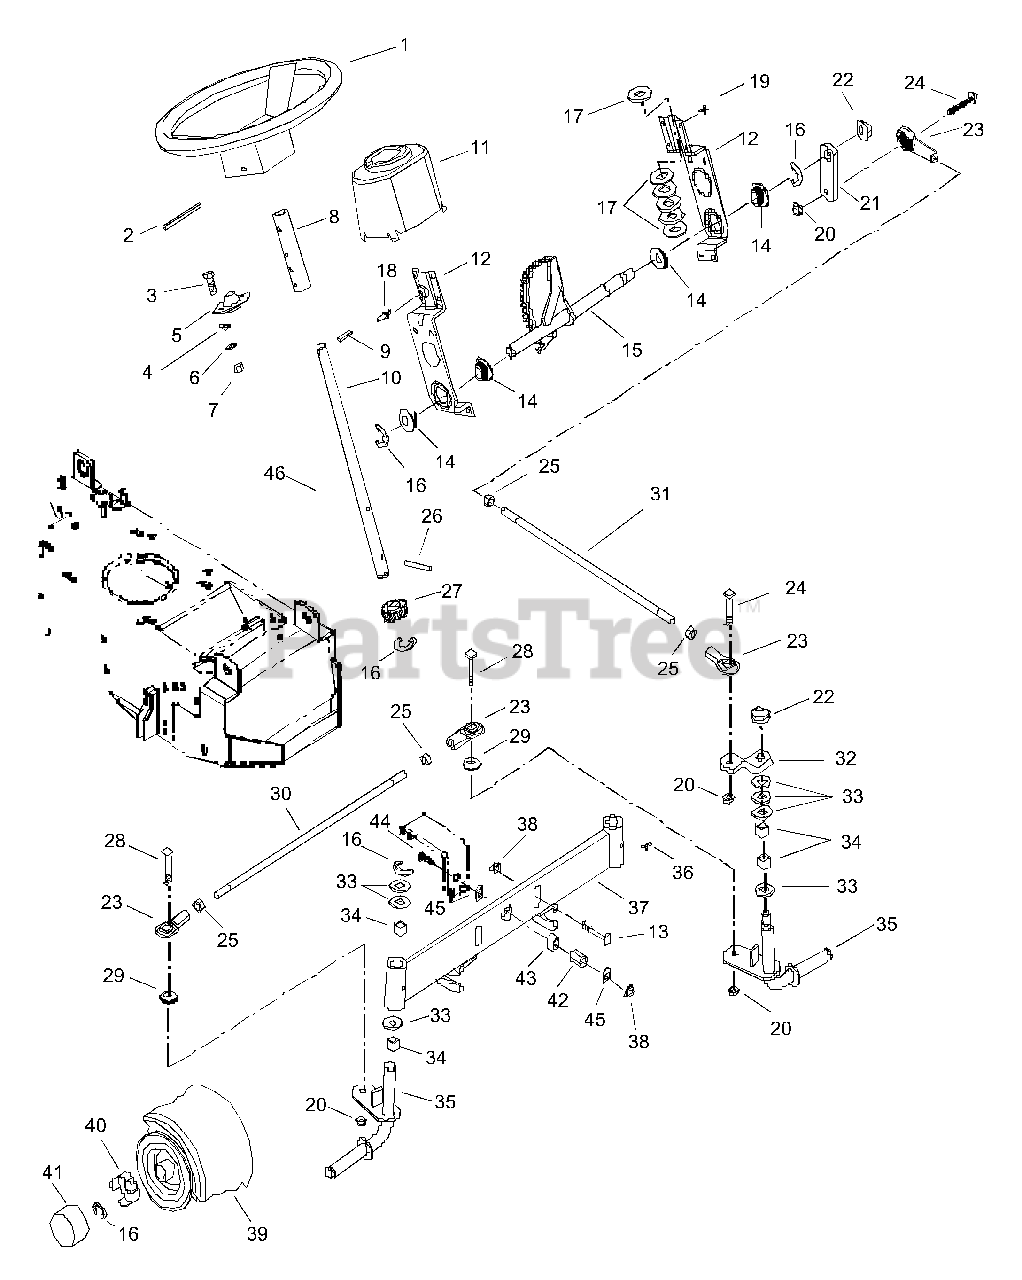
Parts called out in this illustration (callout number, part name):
1	Steering Wheel 13"
2	Pin-Roll .250 x 1.75
3	Bolt-Hex .31-18 x .75 Grade 5
4	Washer-Flat-Steel .312 x .734 x .065
5	Bearing-Flange .751 x 2 Holes x .81
6	Washer-Lock .312 x .097
7	Nut-Hex .312-18
9	Pin-Roll .250 x 1.000
10	Column, Steering
11	Cone-Steering Column
12	Bracket, Steering Gear
13	Bolt-Hex .38-16 x 1.50 Grade 5
14	Bushing-Flange .750 x 1.093 x .625 x 1.375
15	Gear, Steering
16	Ring-Retaining-External .750 x .050
17	Washer-Flat-Steel .755 x 1.375 x .062
18	Fitting-Lube .25-28 x .256
19	Screw-Tapping .250-20 x .37
20	Nut-Locking-Center .375-16
21	Arm, Steering Rod
22	Nut-Locking .563-18-Grade 5
23	Rod End
24	Bolt-Button Head .38-16 x 1.25 Grade 5
25	Nut-Jam .375-24
26	Pin
27	Pinion Gear-Steering
28	Bolt-Hex .38-16 x 1.75 Grade 5
29	Bushing-Sleeve .377 x .624 x .370
30	Rod-Tie
31	Link-Drag
32	Arm-Steering Spindle
33	Washer-Flat-Steel .755 x 1.375 x .062
34	Bushing-Sleeve .750 x .814 x 1.000
35	Spindle Left Hand
35	Spindle Right Hand
36	Fitting-Lube .25-28 x .256
37	Axle, Front
38	Nut-Locking-Center .38-16
39	Tire/Wheel Assembly 15 x 6.00-6
39	Rim
39	Bushing-3/4 Bore
39	Fitting-Lube .25-28 x .97
39	Tire-Turf Saver 15 x 6.00-6 2 Ply
39	Bearing-Ball
40	Spindle Cup
41	Hub Cap
42	Bushing-Sleeve .377 x .623 x .775
43	Bushing-Sleeve .626 x 1.000 x .524
44	Bolt-Hex .38-16 x 1.75 Grade 5
45	Washer-Flat-Steel .390 x 1.500 x .125
46	Pin-Roll .188 x 1.13
